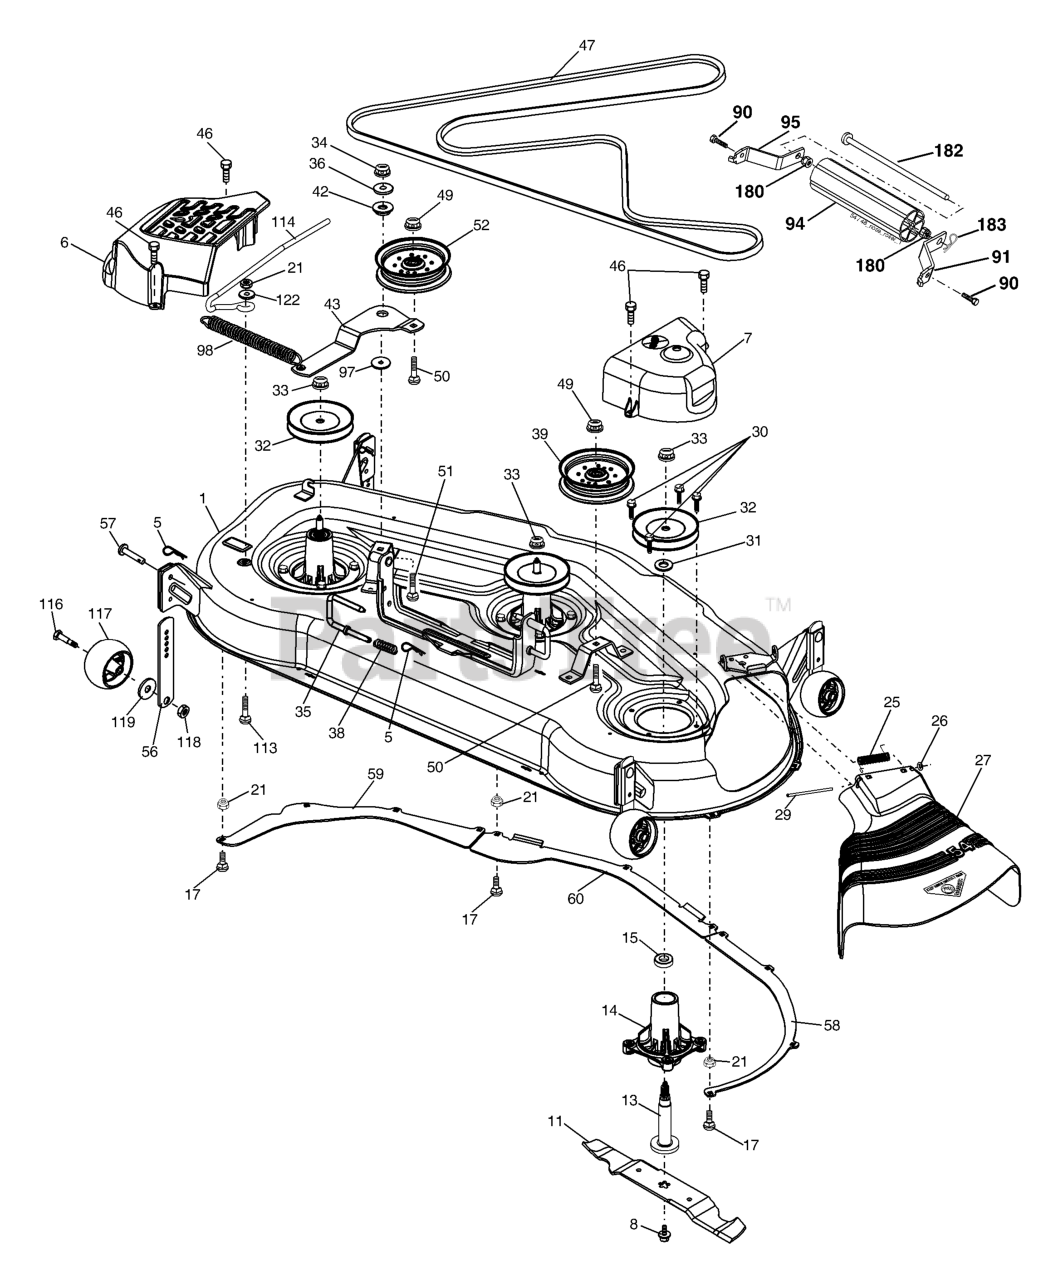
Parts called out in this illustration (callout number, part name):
1	DECK WELDMENT
5	RETAINER-SPRNG RB
6	COVER.MANDREL.LH.DECK.54"
7	COVER.MANDREL.RH.DECK.54"
8	BOLT 7/16 ASM BLADE
11	Blade Standard
13	SHAFT ASM MANDREL
14	RP.HOUSING.MANDREL.4PT.
17	BOLT.CARR.5/16-18X5/8.SHORT
21	LOCKNUT
25	SPRING, TORSION
26	NUT PUSH M
27	DEFLECTOR
28	Washer 11/32 x 5/8 x 16 Ga.
29	ROD.HINGE
30	SCREW, WASHER HEAD
31	WASHER.SPACER.MANDREL
32	PULLEY, MANDREL
33	NUT, FLG TOPLOCK 9/16"
35	PIN.SUSPENSION.REAR.54"
36	WASHER
38	SPRING COMPRESSION PULL
39	PULLEY.IDLER.STATIONARY
41	BUSHING.RELIEF.TENSION
42	SPACER RETAINER
43	ARM IDLER
46	SCREW.1/4-20X5/8
47	V-BELT 54" HIGH PERFORMANCE
49	NUT LOCK FLG 3/8-16 UNC
50	BOLT
51	BOLT
52	IDLER PULLEY
56	BAR.ADJUST.WHEEL.ANTI.SCALP.BL
57	RIVET.PIN.HEAD.YELLOW.
58	BAFFLE.RIGHT.54"
59	BAFFLE.LEFT.54"
60	BAFFLE CENTER 54" MOWER
90	BOLT RB
91	BRKT.NOSEROLLER.RH.48"
94	NOSE ROLLER 48"
95	BRKT.NOSEROLLER.LH.48"
97	WASHER 12/32X2X10GA
98	SPRING.CLUTCH.DRIVE.54
101	MULCH COVER 54"
102	SCREW
103	LOCKWASHER #10
105	WELDNUT
113	BOLT CRT
114	ROD TENSION RELIEF
116	SHOULDER BOLT
117	WHEEL GAGE DONUT
118	LOCKNUT
119	WASHER.5/16.FLAT.STE.STD.
122	BUSHING.RELIEF.TENSION
180	NUT.71038.31-18.HEX.NYLOCK
182	ROD.ROLLER.NOSE.NARROW.48"
183	SPRING RETAINER
